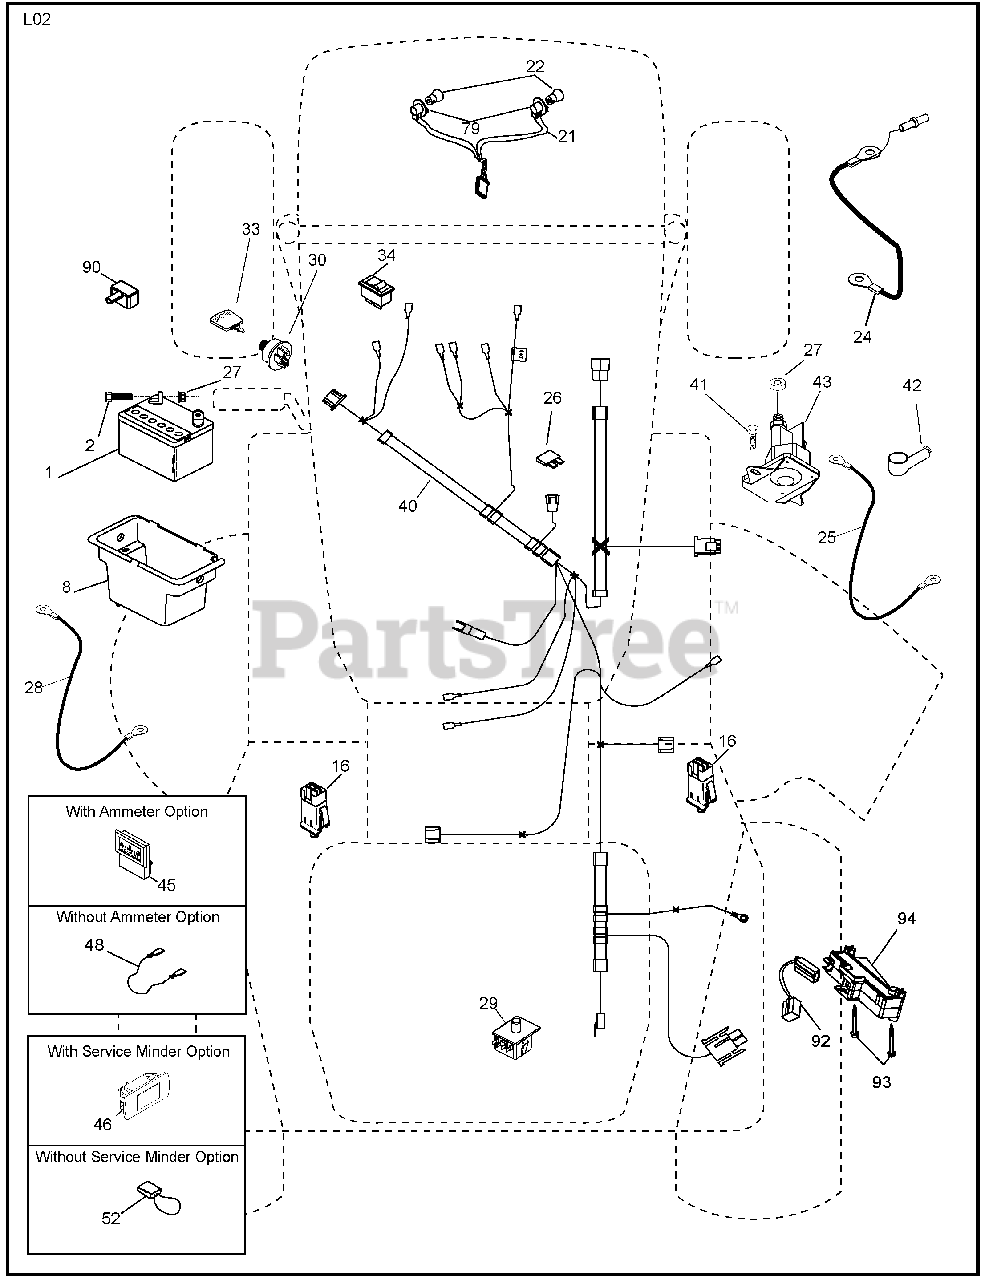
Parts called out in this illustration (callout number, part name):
1	Battery
2	Bolt Hex Hd 1/4-20 unc x 3/4
8	Box Battery
16	Switch Interlock
21	Harness Asm Light W/4152j
22	Bulb Light #1156
24	Cable Battery 6 Ga. 11"red
25	Cable Battery
26	Fuse 20 AMP
27	Nut Keps Hex 1/4-20 unc
28	Cable Ground 6 Ga. 12"black
29	Switch
30	Switch Ign
33	Key/Chain
34	Switch Light/Reset
40	Harness Ign
41	Bolt Blk Fin Hex 1/4-20
42	Cover Terminal Red
43	Solenoid
48	Adapter Ammeter
52	Protection Wire Loop
79	Socket Asm. Bulb
90	Cover Terminal Battery
92	Harness Pigtail
93	Screw Plastite 10-14 x 2.0
94	Module Reverse
